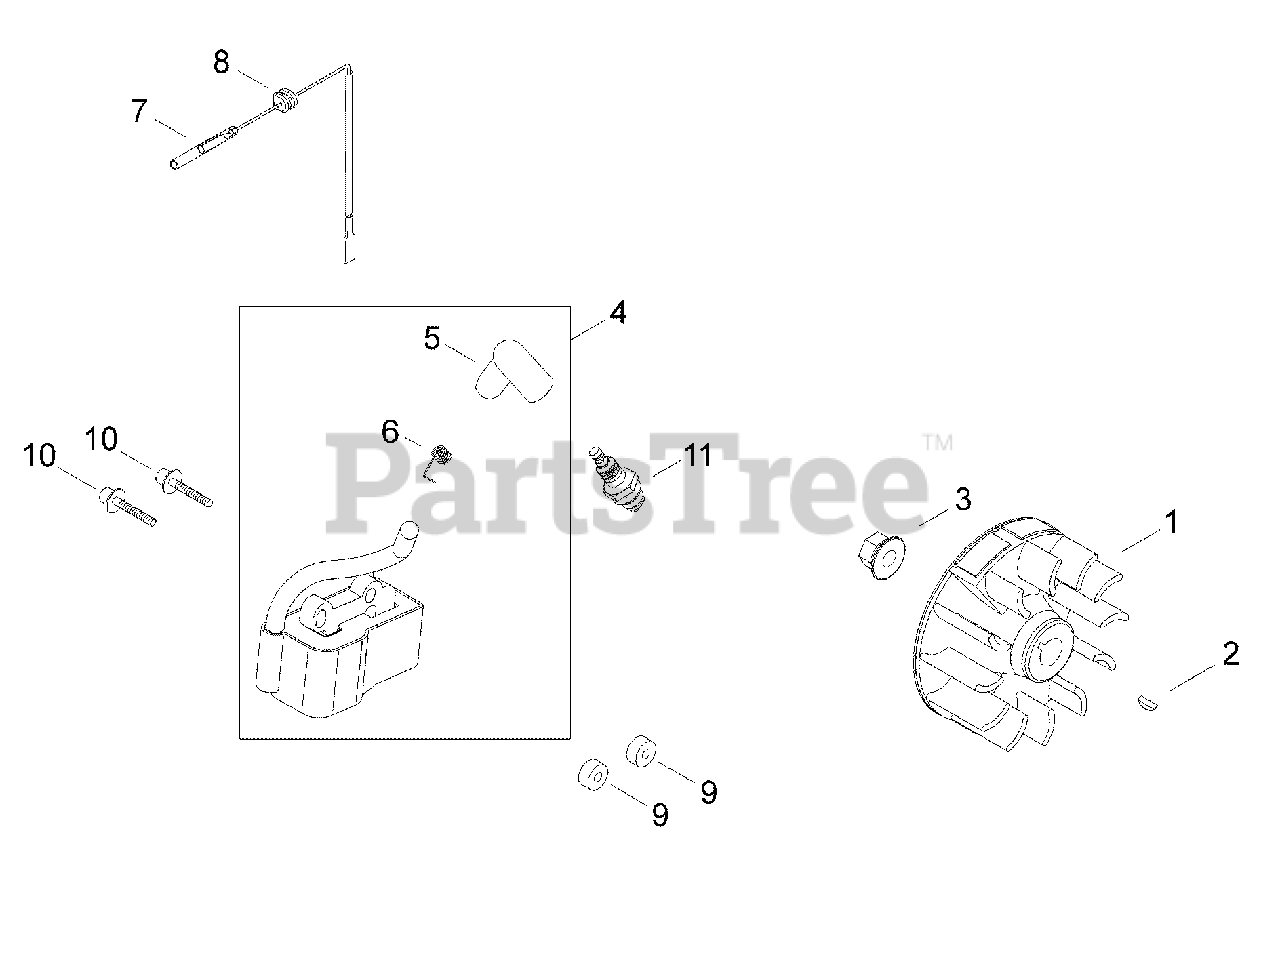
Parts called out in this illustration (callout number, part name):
1	FLYWHEEL
2	KEY - 3X10
3	NUT - 8
4	IGNITION COIL ASSY
5	CAP, SPARK PLUG
6	TERMINAL, SPARK PLUG CAP
7	LEAD - IGNITION
8	GROMMET
9	INSULATOR
10	SCREW - 4X26
11	SPARK PLUG -- CMR-5H
